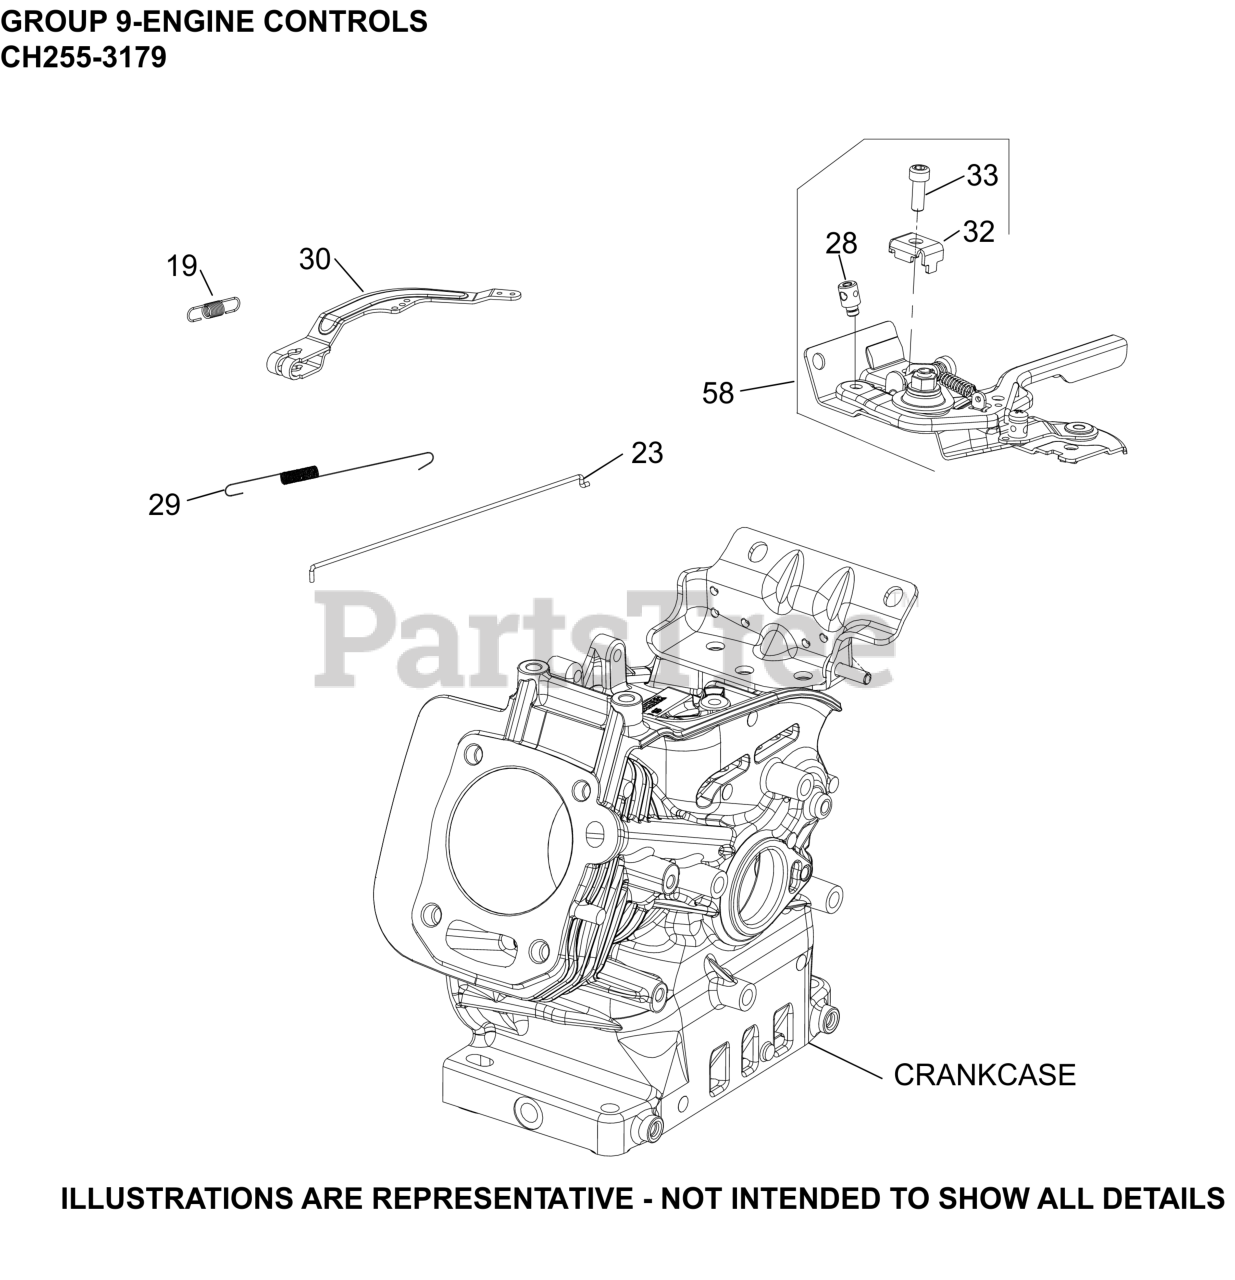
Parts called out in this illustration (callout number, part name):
19	SPRING, GOVERNOR
23	LINKAGE, GOVERNOR-USE 18 079 05-S
28	KIT, CABLE CLAMP
29	SPRING, LINKAGE
30	KIT, GOVERNOR LEVER
32	CLAMP, CABLE
NI	VARIABLE SPEED CONTROL ASSEMBLY
